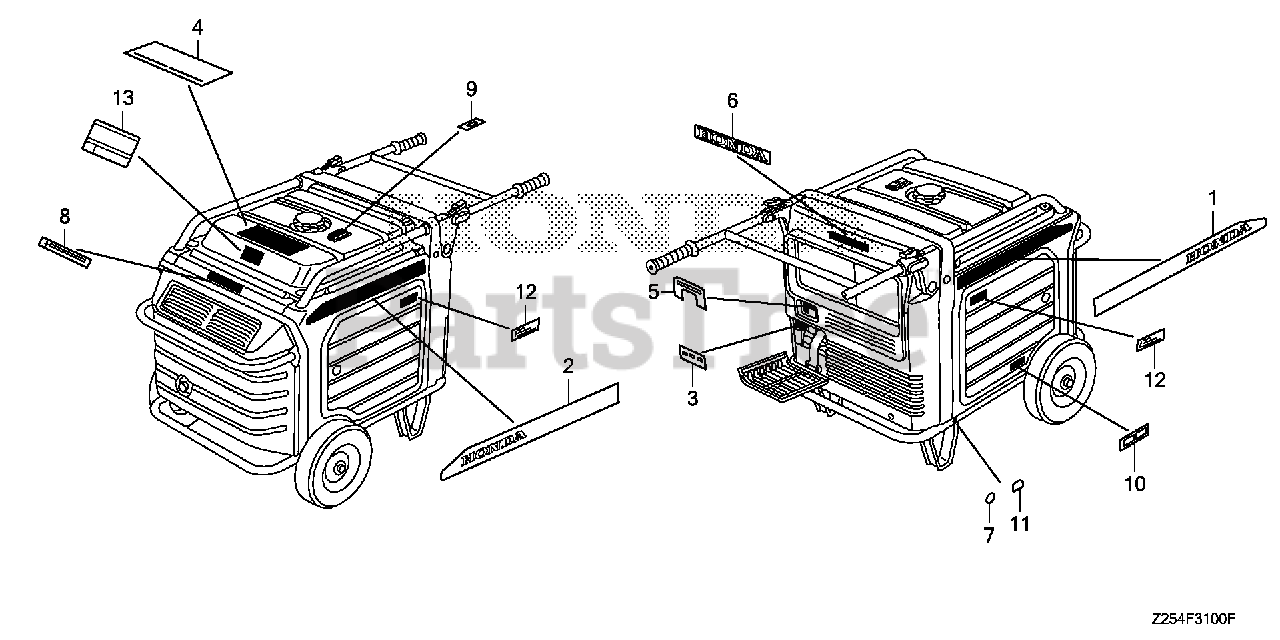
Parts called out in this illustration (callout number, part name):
1	MARK, EMBLEM (R)
2	MARK, EMBLEM (L)
3	MARK, BRANCH FUSE (E)
4	LABEL, OPERATOR WARNING (E)
5	MARK, PANEL SWITCH
6	MARK, HONDA
7	MARK, GROUND
8	MARK, EX. CAUTION
9	PLATE, FUEL INDICATION
10	MARK, OIL CAUTION
